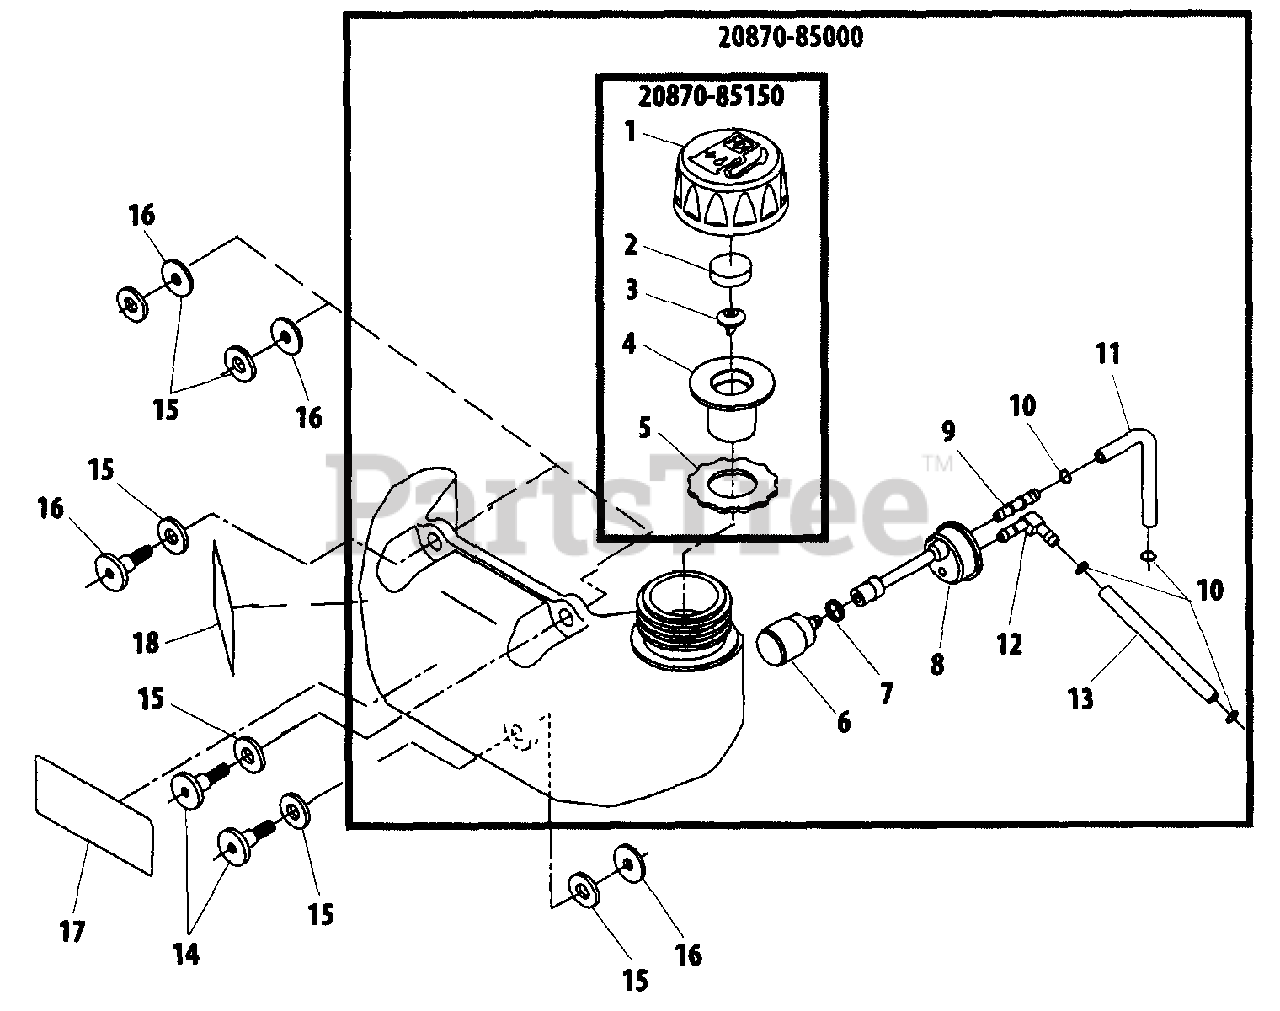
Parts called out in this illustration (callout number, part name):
1	CAP, FUEL
2	COVER, VENT
3	VENT
4	HOLDER, VENT
5	GASKET, CAP
6	FILTER, FUEL
7	RING, RETAINING
8	FUEL PIPE ASSY
9	CONNECTOR, PIPE
10	RING, RETAINING - 6
11	PIPE - FUEL
12	CONNECTOR, PIPE
13	PIPE - RETURN
14	BOLT
15	WASHER
16	WASHER
17	LABEL - CAUTION
18	LABEL
20870-85000	FUEL TANK ASSY
20870-85150	CAP ASSY
